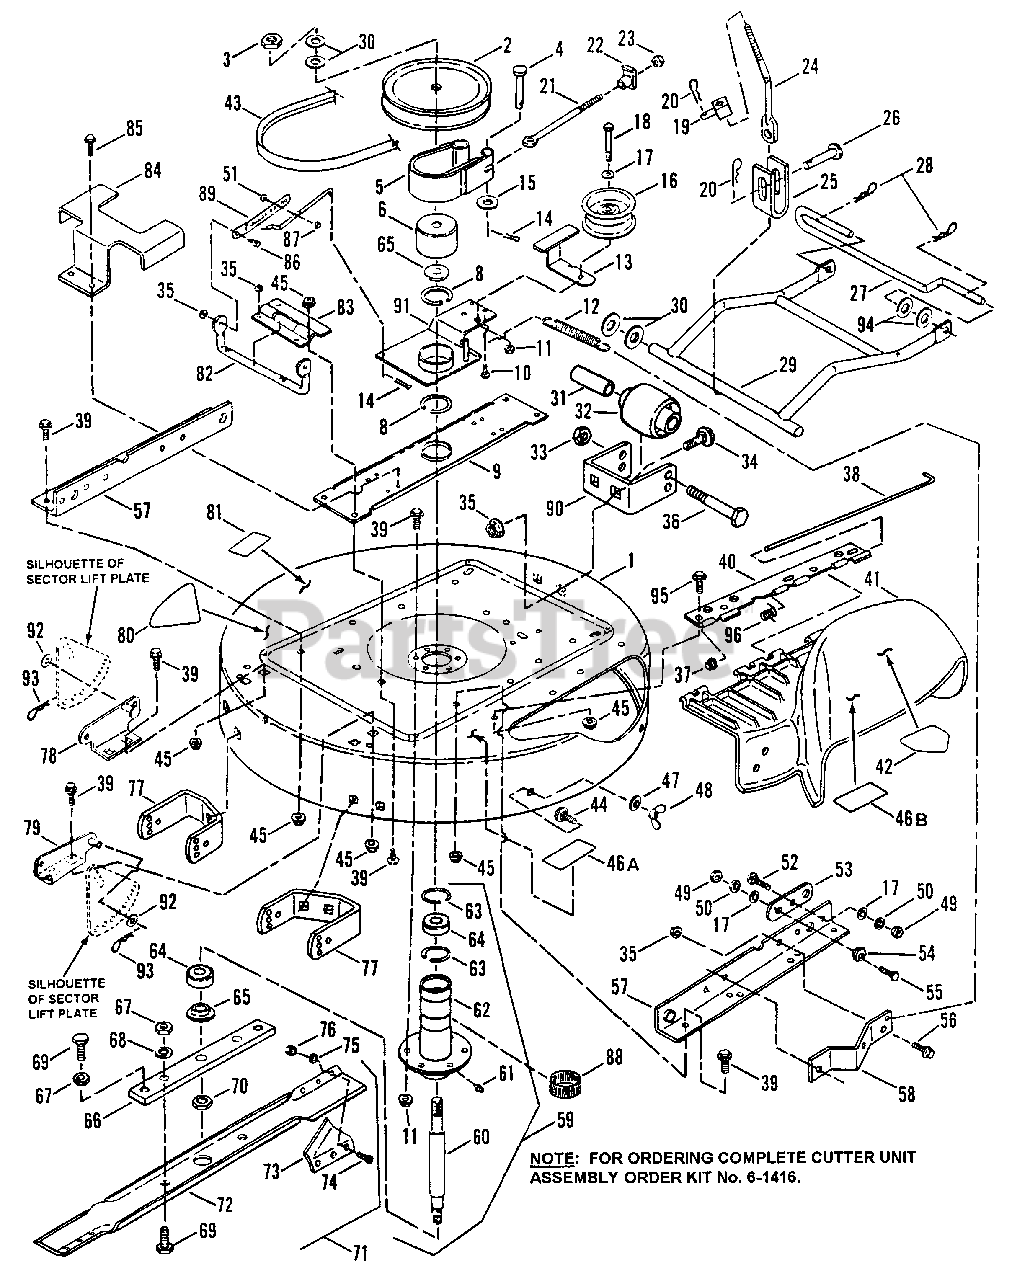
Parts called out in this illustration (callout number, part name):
1	ASSEMBLY, Deck, 33" Cutting
2	PULLEY, Spindle, 7" O.D.
3	NUT, 3/4-16 Hex Jam
4	PIN, 1/4 x 1 1/4" Clevis
5	ASSEMBLY, Brake Band
6	DRUM, Brake
7	ROD, Link, Clutch/Brake
8	RING, 2" External Retaining
9	BRACE, Spindle
10	SCREW, 5/16-18 x 3/4" Self-Tapping
11	NUT, 3/8-16 Hex Center Lock
12	SPRING, Clutch & Brake
13	GUIDE, Belt
14	COTTER-PIN, 3/32 x 3/4"
15	WASHER, Flat
16	PULLEY, Idler, 4" O.D.
17	WASHER, 3/8 SAE Flat
18	SCREW, 3/8-16 x 1 3/4" Hx. Hd. Cap
19	SWIVEL, Brake
20	PIN, 1/4 x 1 1/8" Hair
21	BOLT, 1/4-20 Eye
22	NUT, 1/4-20 Tee
23	NUT, 1/4-20 Hex
24	ROD, Front Lift
25	BRACKET, Front Lift Hanger
26	PIN, 3/8 x 1 1/2" Clevis
27	PIN, Front Deck Hanger
28	PIN, Hair, .148 x 2.62"
29	LIFT, Front Arm
30	WASHER, Flat
31	SPACER
32	WHEEL, Gage
33	NUT, 3/8-24 Hex Center Lock
34	BOLT, 5/16-18 x 1/2" Short Neck Carriage
35	NUT, 5/16-18 Hex Flange Lock
36	SCREW, 3/8-24 x 3 3/4" Hex Head Cap, Grade 5
37	PALNUT, 1/4 Hex
38	PIN, Hinge
39	BOLT, 3/8-16 x 3/4" Hx. Flge. Lk.
40	HINGE, Deflector
41	DEFLECTOR, Discharge
41	ASSEMBLY, Deflector
42	DECAL, Danger (Cut Finger)
43	BELT, Drive, 33" Cutting Deck, 56.95" EL
44	BOLT, 5/16-18 x 3/4" Short Neck Carriage, Grade 5
45	NUT, 3/8-16 Hex Flange Lock
46A	DECAL - CAUTION
46B	DECAL - CAUTION, Deflector
47	WASHER, 5/16 Flat
48	NUT, 5/16-18 Wing
49	NUT, 3/8-16 Hex
50	WASHER, 3/8 Split Lock
51	BOLT, 1/4-20 x 1/2" Hex Flange Lock
52	BOLT, 3/8-16 x 3/4" Carriage
53	LINK, Adjustment
54	ECCENTRIC, Leveling
55	SCREW, 3/8-16 X 1" Hex Head Cap
56	BOLT, 5/16-18 x 1/2" Hex Flange Lock
57	RAIL, Side
58	ANCHOR, Brake
59	ASSEMBLY, Spindle
60	SPINDLE, 7.54" Long
61	FITTING, Lube (Press fit for .187 hole-no ball)
62	HOUSING, Spindle
63	RING, Retaining
64	BEARING, Spindle
65	WASHER, Spindle
66	HOLDER, Blade
67	NUT, 1/2-20 Hex Jam
68	WASHER, 1/2 Int. Tooth Lock
69	SCREW, 1/2-20 Hex Head Cap
70	NUT, 5/8-18 Hex Lock
71	ASSEMBLY, Blade & Air Lift
72	BLADE, 33" Cutting Deck
73	AIR-LIFT
74	SCREW, 5/16-24 x 11/16" Machine
75	WASHER, 5/16 Int. Tooth Lock
76	NUT, 5/16-24 Hex
77	BRACKET, Gage Wheel (Rear)
78	BRACKET, Rear Deck Lift, Left Side
79	BRACKET, Rear Deck Lift, Right Side
80	DECAL, 33" Hi-Vac
81	DECAL - CAUTION (Rotating Blades)
82	ARM, Pivot
83	BRACKET, Pivot Arm
84	GUIDE, Belt
85	SCREW, 5/16-18 x 5/8" Self-Tap.
86	SCREW, 5/16-18 x 3/4" Shoulder
87	NUT, 1/4-20 Hex Flange Lock
88	RING, Tolerance
89	BRACKET, Link, Clutch/Brake
90	BRACKET, Gage Wheel (Front)
91	ARM, Idler
92	WASHER, 3/8" Flat
93	PIN, Hair, .093 x 1.50"
94	WASHER, Flat
95	BOLT, 3/8-16 x 3/4" Hex Flange Lock, Grade 5
96	SPRING, Hinge
